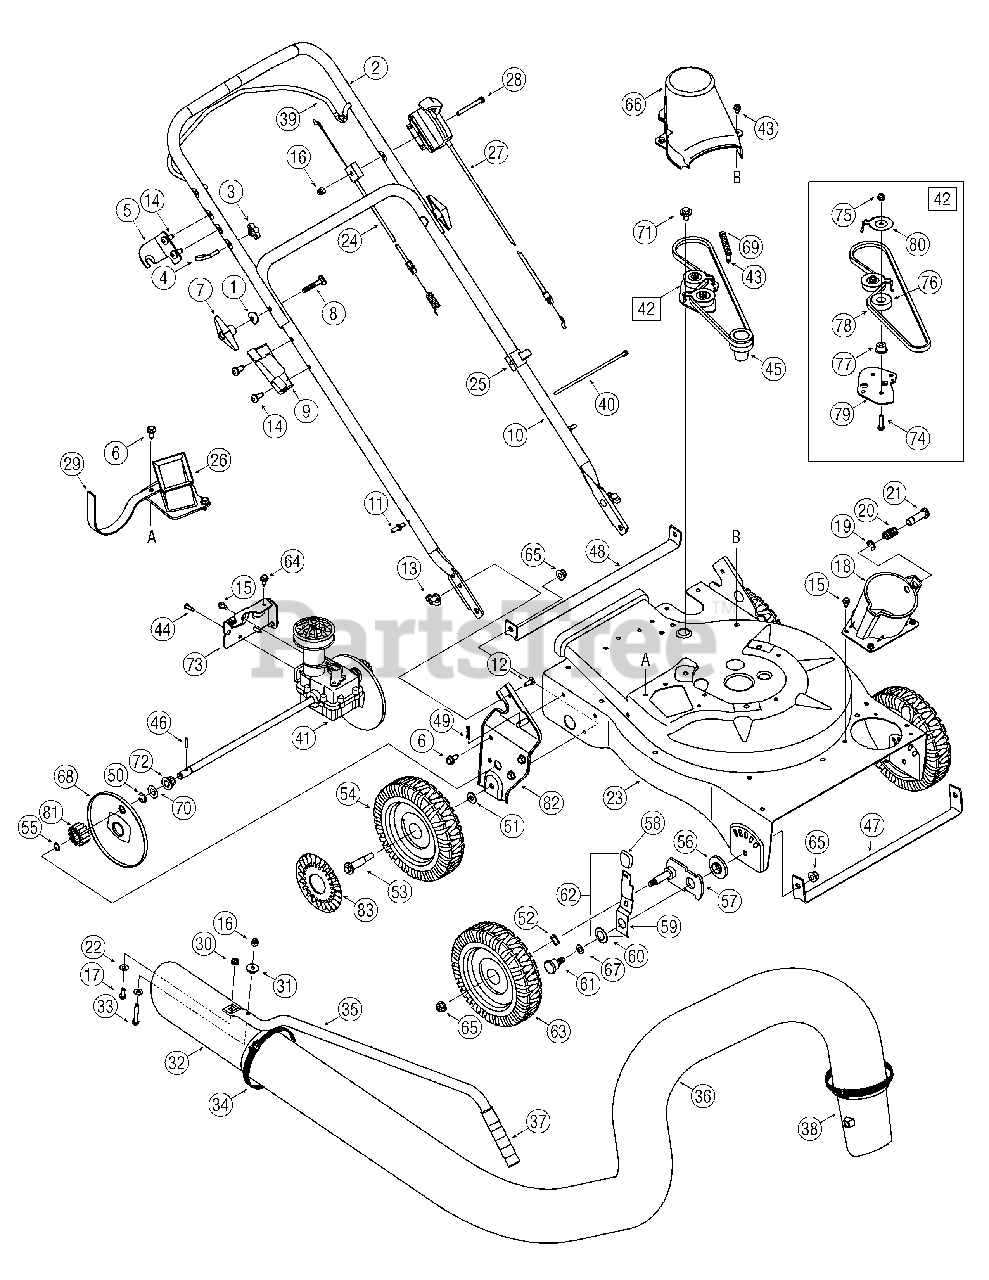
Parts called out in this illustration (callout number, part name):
1	Saddle Washer, .320 x.93
4	Eye Bolt
6	Hex Cap Screw 5/16-12 x.750
7	Handle Knob 5/16-18
8	Carriage Bolt
9	Nozzle Handle Clip
11	Studs
12	Carriage Screw 1/4-20 x.75
13	Wing Nut 1/4-20
14	TT Screw, 5/16-18 x .750
15	Screw, 1/4-20 x .500
16	Cap Lock Nut, 1/4-20
17	Hex Cap Screw 1/4-20 x.620
18	Hose Base Adapter Assembly (Incl. Ref.# 19-21)
19	E Ring.500 Dia
20	Compression Spring
21	Clevis Pin
22	Flat Washer.271 ID x.630 OD
25	Cable Guide
27	Speed Control Cable
28	Hex Screw, 1/4-20 x 2.50
31	Spacer
32	Hose Nozzle
33	Hex Cap Screw 1/4-20 x 2.625
34	Adjustment Clamp
36	Vacuum Hose
37	Handle Grip
38	Hose Adapter
39	Drive Control
40	Cable Tie
41	Transmission Assembly
42	Idler Assembly (Incl. Ref.# 74-80)
43	Shoulder Screw, #12-24 x .30 x .46
44	Screw, #12-16 x .750
45	Impeller Hub
46	Dowel Pin
49	Cotter Pin
50	E-Ring
51	Flat Washer, .385 x 1.00 x .135
52	Wave Washer.531 ID x.781 OD
53	Shoulder Screw 3/8-16
54	Wheel, 8 x 2.125
55	Snap Ring
56	Height Adjustment Bearing
57	Pivot Arm Assembly
58	Height Adjustment Knob
59	Spring Lever
60	Bell Washer.760 ID x.25 OD
61	Shoulder Screw,.750 x.500
62	Height Lever Assembly (Incl. Ref.# 58-59)
63	Wheel 8 x 2
64	Screw, 1/4-20 x .625
65	Flange Lock Nut, 3/8-16
66	Belt Cover
67	Thrust Washer.375 ID x.70 OD
68	Wheel Cover
69	Extension Spring,.375 x 2.95
70	Flat Washer,.508ID x1.00OD x.020
71	Shoulder Screw,.560 x.165
72	Drive Axle Bushing
74	Screw, 1/4-20 x 1.00
75	Flange Lock Nut, 1/4-20
76	Ball Bearing
77	Flange Spacer,.260 x.659 x.517
78	Belt, 3/8 x 32.5
80	Belt Keeper
81	Spur Gear - RH
83	Hub Cap
